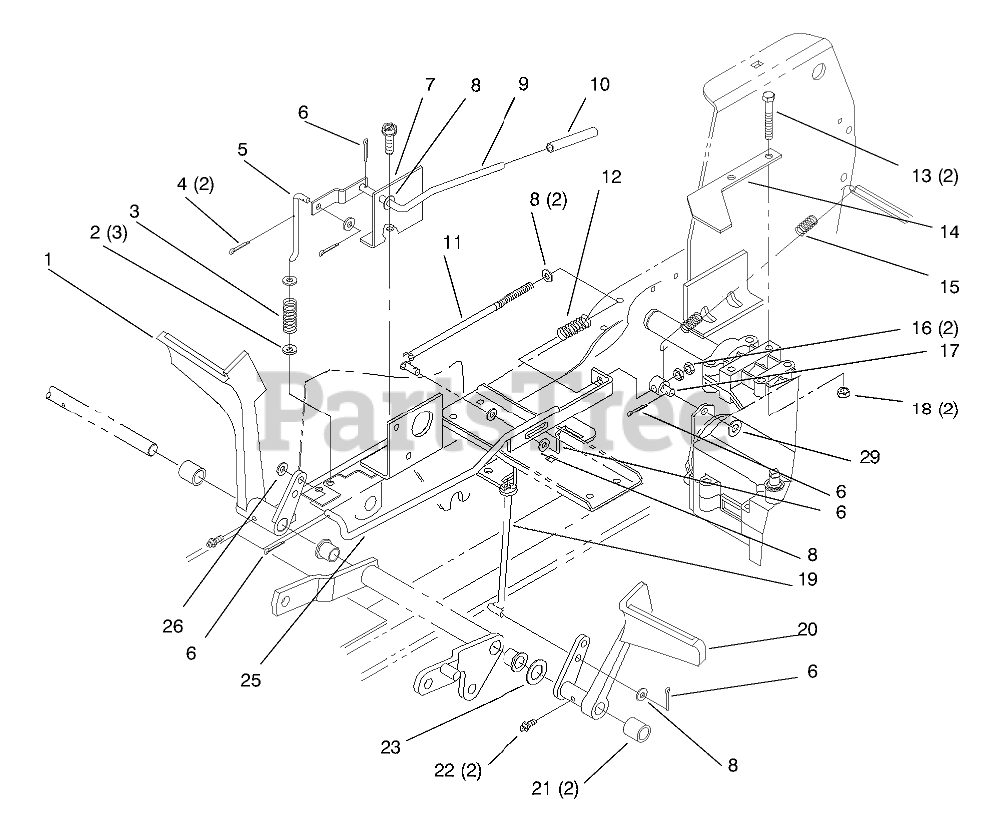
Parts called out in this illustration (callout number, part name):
1	Pedal-Brake
2	WASHER-FLAT
3	SPRING - COMPRESSION
4	PIN-COTTER
5	ROD - PARKING BRAKE
6	PIN-COTTER
7	BRKT-PARKING BRAKE
8	WASHER-PLAIN
9	PARK BRAKE LVR WAB
10	GRIP - PARKING BRAKE
11	ROD - SPRING
12	SPRING - COMPRESSION
13	SCREW-HH
14	STOP - BRAKE
15	SPRING - EXTENSION
16	NUT-JAM
17	TRUNION
18	NUT-LOCK, NI
19	CLUTCH ROD WA
20	PEDAL-CLUTCH
21	SPACER
22	FITTING-GREASE
23	WASHER-WAVE
25	ARM-BRAKE
26	WASHER-FLAT
29	WASHER-FLAT
